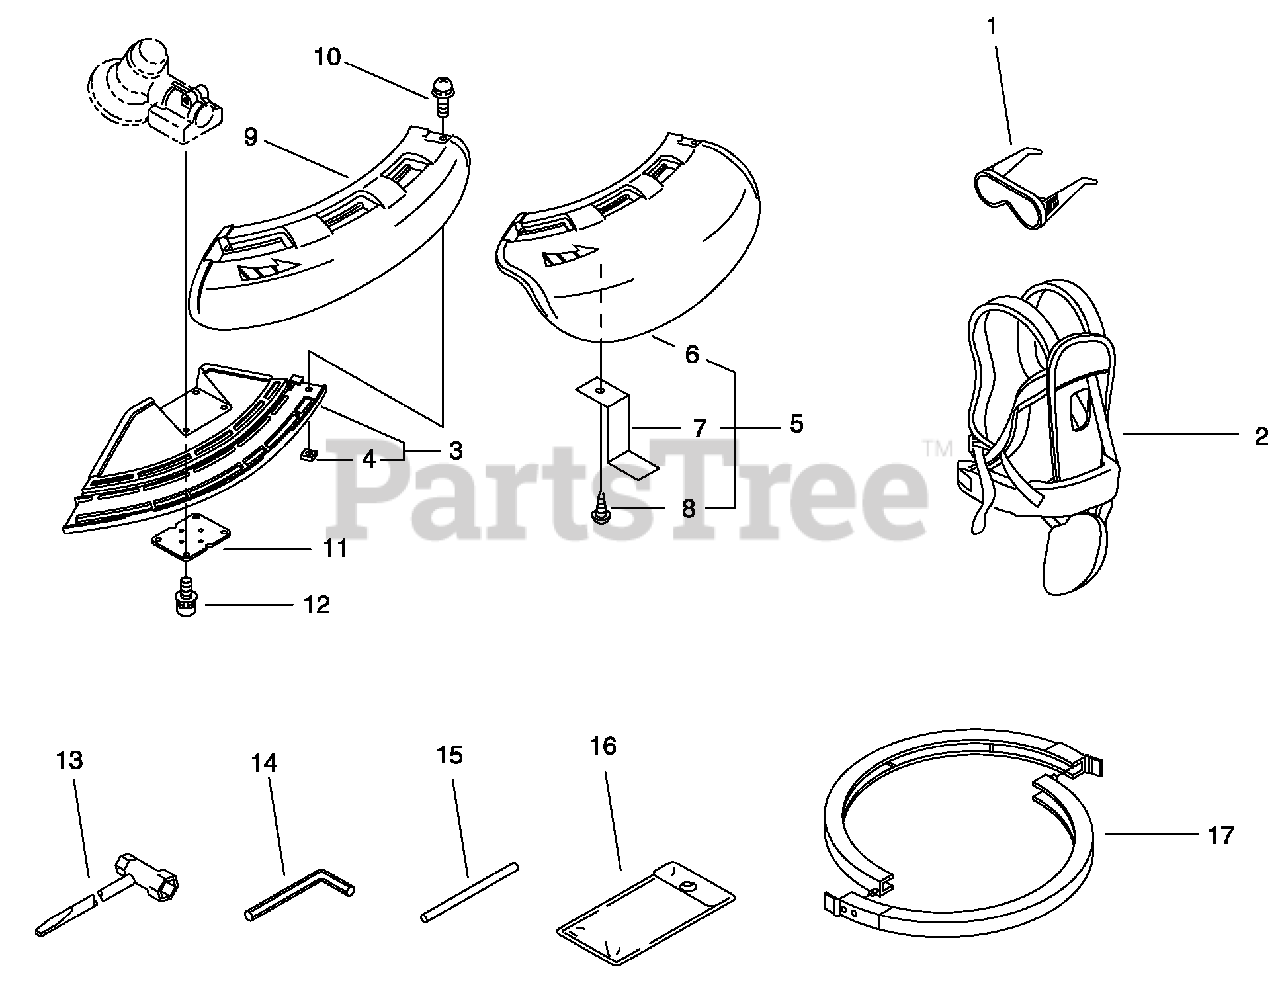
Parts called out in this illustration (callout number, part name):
1	GLASSES, SAFETY
2	HARNESS, SHOULDER
3	BRACKET ASSY, SHIELD
4	NUT M5
5	DEBRIS SHIELD ASSY
6	SHIELD, DEBRIS
7	CUTTER, LINE
8	SCREW, TAPPING 5×12
9	SHIELD, BLADE
10	BOLT 5×22
11	PLATE, SHIELD
12	BOLT 5×25
13	T-WRENCH 17x-19 L200
14	WRENCH, ALLEN 4 MM
15	TOOL, LOCKING 5×120 MM
16	BAG, TOOL
